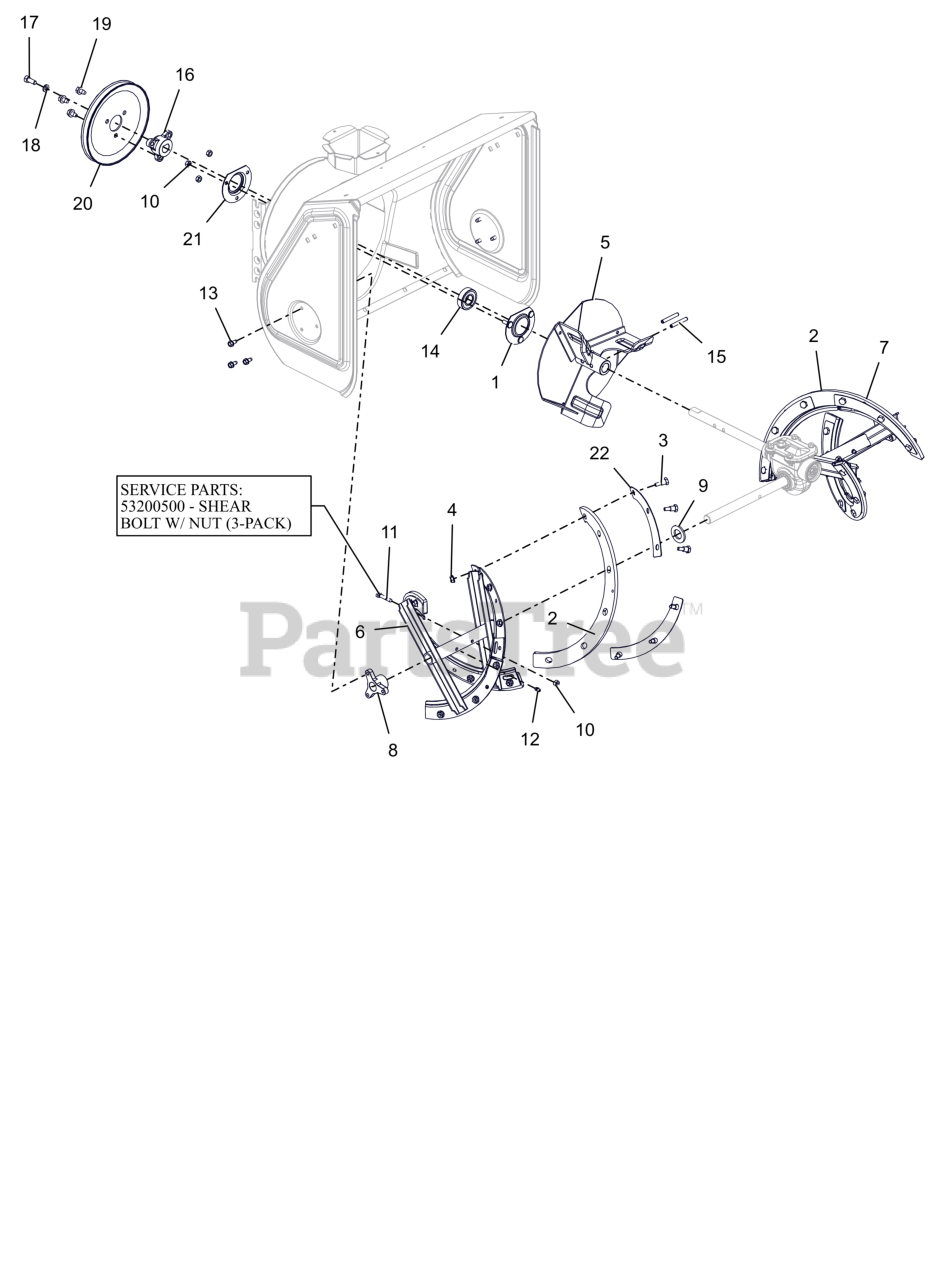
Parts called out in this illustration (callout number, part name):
1	BEARING FLANGE
2	KIT, RUBBER FLIGHTING RAKE
3	BOLT, SHLDR -.375 X .375 X .25-20
4	NUT-LK-CTR-FLG .25-20 ZC120
5	IMPELLER, 10" 3-BLADE LG BACK (BLACK)
6	WLDMT, AUGER 20" GROUND - RH (BLACK)
7	WLDMT, AUGER 20" GROUND - LH (BLACK)
8	BUSHING, RAKE SHAFT .75"
9	WSHR, FLT .812X1.469X.134 ZCC
10	NUT,LK-CTR .25-20 GA ZCC
11	SHEAR BOLT WITH NUT
12	ZERK,FITTING .25X.125 DRIVE IN
13	SCR-TAP .25-20X.50 HWH ZCC
14	BRG-BALL .750X1.750X.50
15	PIN-ROLL .250X1.75
16	PULLEY HUB, BOLT-ON D-BORE .75
17	BLT, HEX .31-24X.750 G5 ZCC
18	WSHR, LK-HVY .312X.097 ZCC
19	SCR,TAP .312-18X.50 HWH TR ZCC
20	PULLEY, V 7.000 X 1.375 3BLT
21	BEARING FLANGE
22	BRACE, RUBBER FLIGHTING
